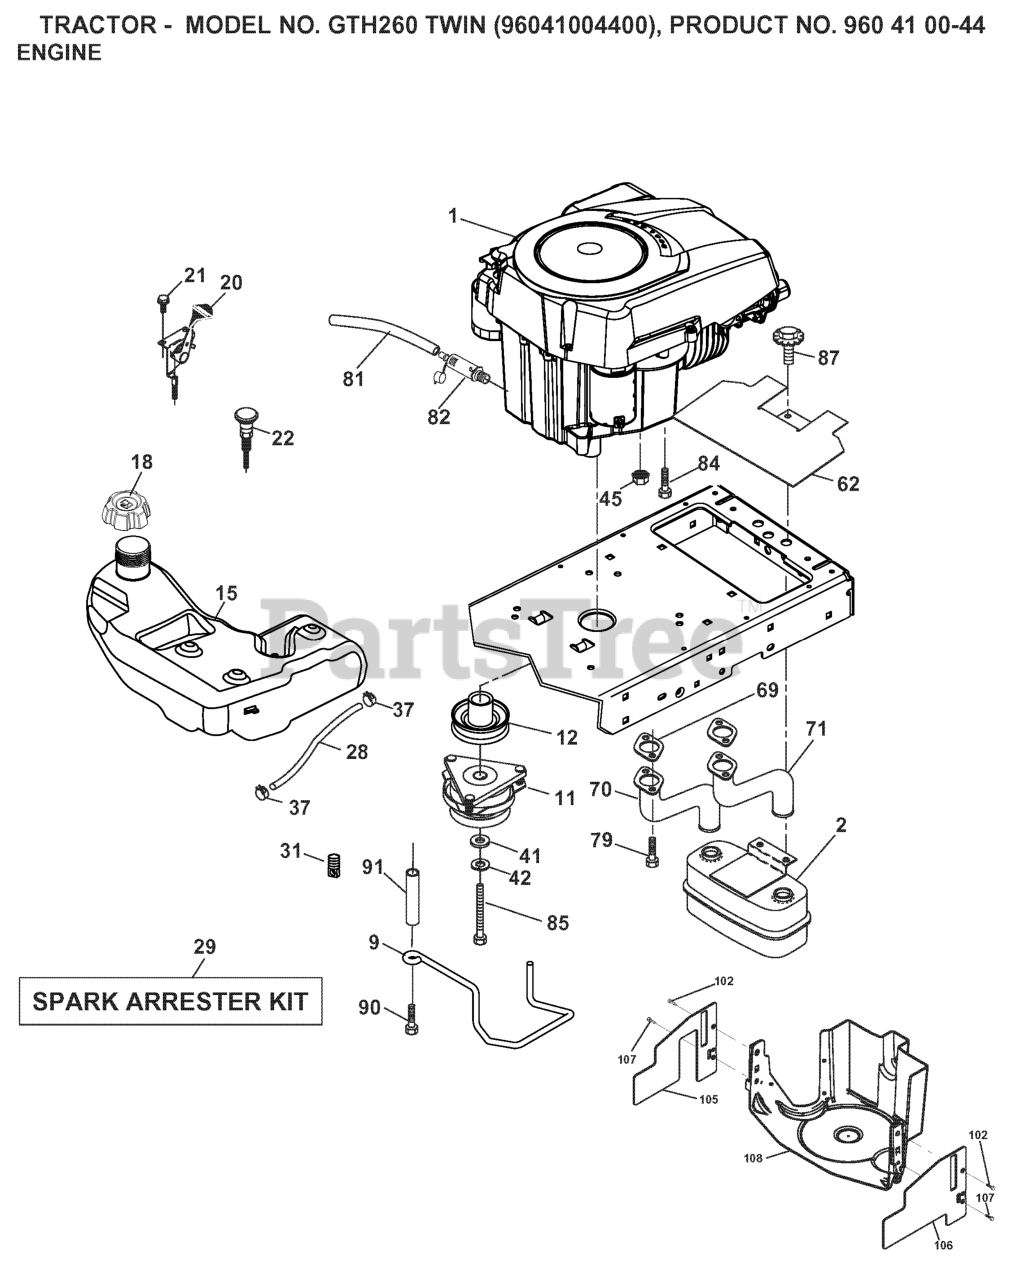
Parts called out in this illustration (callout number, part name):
2	MUFFLER.TWIN.CYL.LOW.TONE
9	KEEPER.BELT.ENGINE.4.2
11	CLUTCH MZ ZTR GT.48/54"1.125"
12	PULLEY ENGINE
15	TANK.FUEL.4GAL
18	CAP.FUEL.TANK.3"GREY
20	THROTTLE CONTROL
21	SCREW
22	CONTROL.CHOKE.ERGO.PUSH-IN.BLA
28	FUEL LINE 54"
29	KIT.SPARK ARRESTOR 794945 B&S
37	HOSE CLAMP
42	LOCKWASHER
45	NUT
62	RP SHIELD HEAT MUFFLER
70	RP.PIPE-EXHAUST LH
71	RP.PIPE-EXHAUST RH
79	SCREW.SOCKET HD.5/16-1
81	TUBE, DRAIN OIL ASM.
82	PLUG DRAIN OIL EASY
84	SCREW 3/8-16X1
85	BOLT HEX 7/16-20 X 3.75 GR. 5
87	BOLT.5/16-18UNCX1.W/SEMS.BLK
90	SCREW 3/8-16X1
91	BUSHING.1.375OD
102	SCREW
105	SHIELD SIDE
106	SHIELD SIDE
107	SCREW.1/4-20X5/8
